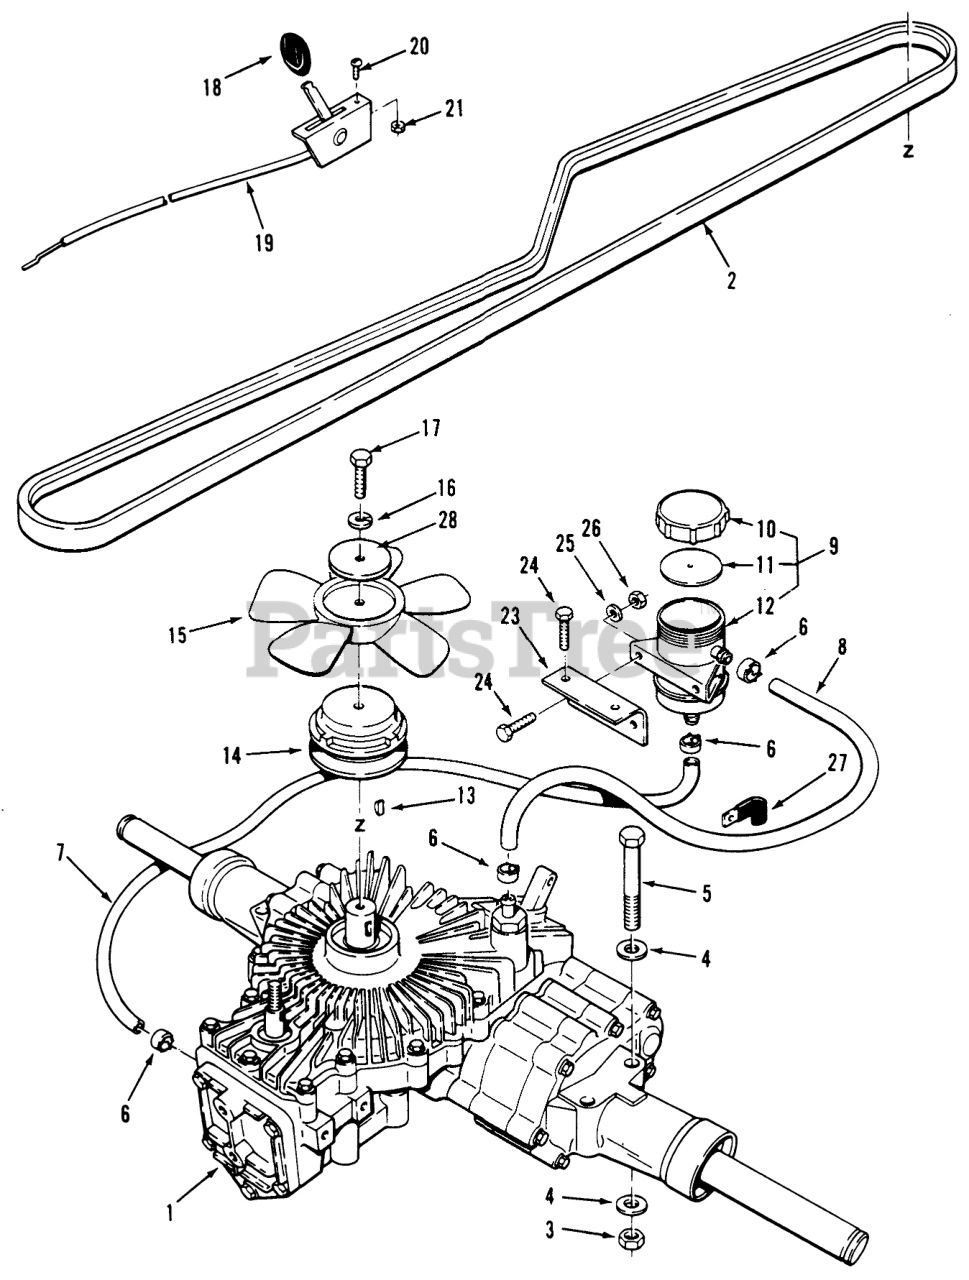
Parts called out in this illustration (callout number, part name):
1	TRANSMISSION 750-019
1	Hydrostatic Transaxle (Eaton Model 750-012)
1	Rebuilt Hydromatic Transaxle
2	BELT V
3	NUT-LOCK, NI
4	WASHER-PLAIN
5	SCREW-HH
6	CLAMP
7	S/A 27" OF 114702
8	S/A 9" OF 114702
9	Reservoir Assembly (Incl. Ref. #10-12)
10	Cover
11	COVER GASKET
12	RESERVOIR
13	Key-Hi-Pro
14	PULLEY-HYDRO
15	BLADE-FAN
16	Washer
17	Bolt
18	KNOB-THROTTLE
19	CABLE-PUSH VALVE
20	Screw
21	Nut
23	BRKT-RESERVOIR MT R
24	SCREW-HH
25	WASHER-FLAT
26	NUT-LOCK, NI
27	CLIP
28	WASHER
